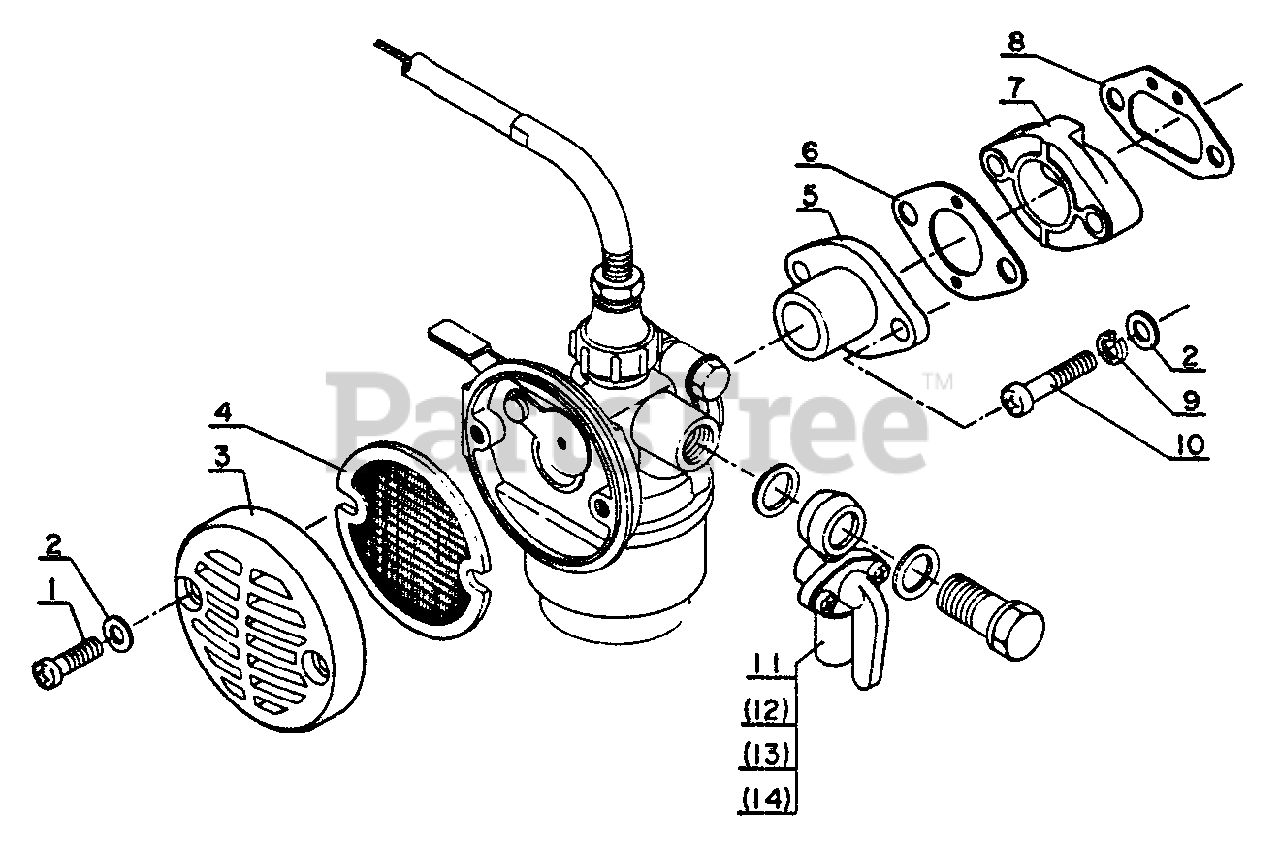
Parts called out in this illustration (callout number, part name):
1	SCREW - 4×12
2	WASHER 4 MM
3	FILTER, AIR
4	COVER, AIR FILTER
5	ADAPTER, INTAKE
6	GASKET, INTAKE
7	INSULATOR, INTAKE
8	GASKET, INTAKE
9	WASHER, SPRING 4 MM
10	SCREW - 4×25
11	FUEL VALVE ASSY
